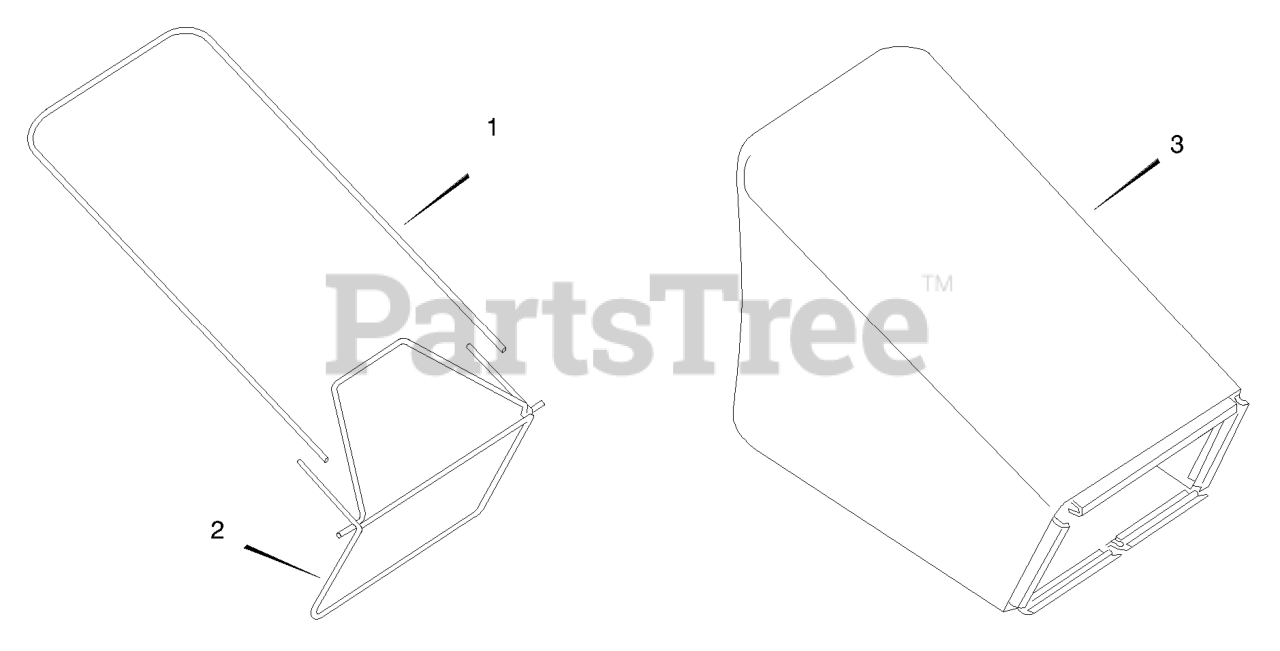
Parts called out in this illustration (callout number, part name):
1	Support, Bag
2	Frame Assembly
3	Bag, Cloth
